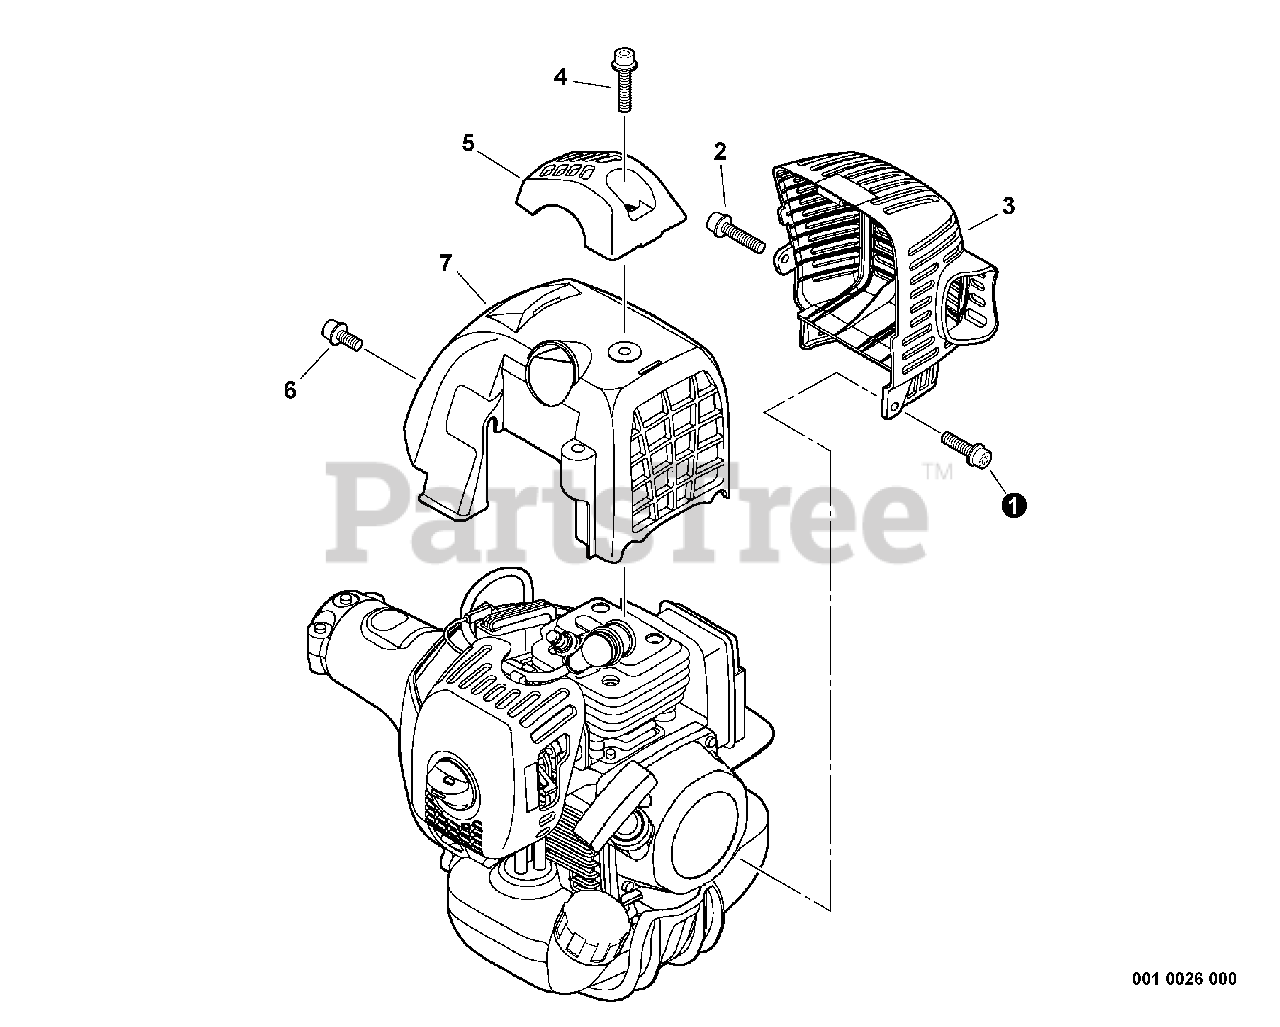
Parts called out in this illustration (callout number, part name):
1	SCREW 5×16
2	BOLT 5×20
3	COVER, MUFFLER
4	BOLT 5×20
5	GUARD, TOP
6	SCREW 5×10
7	COVER, ENGINE
